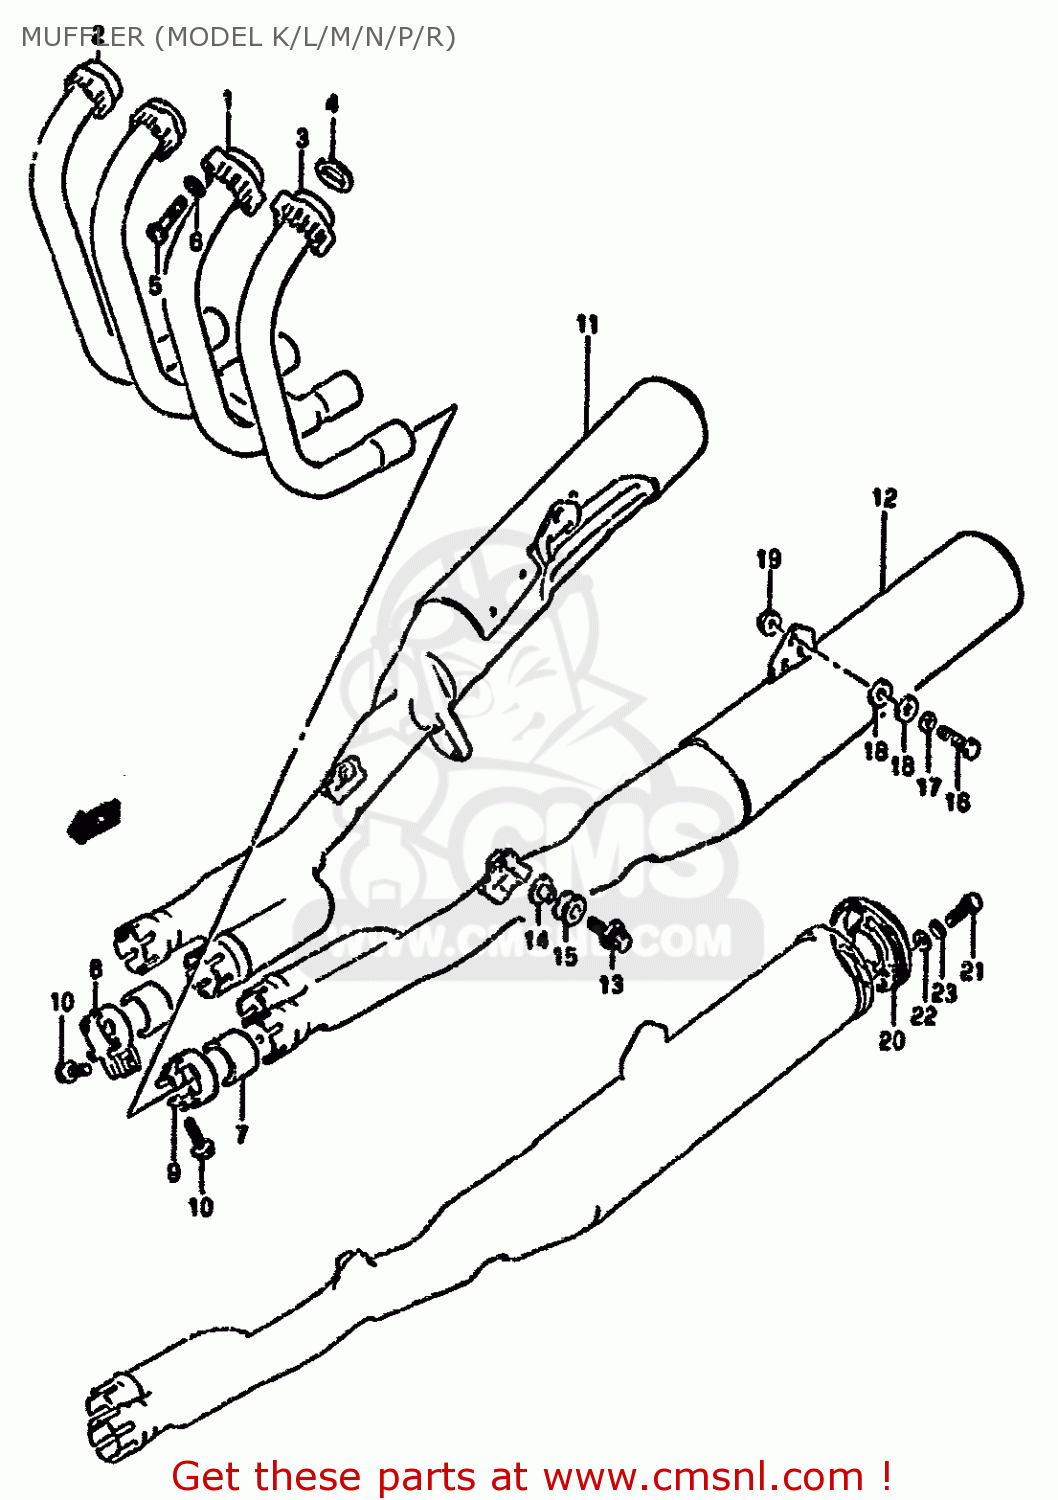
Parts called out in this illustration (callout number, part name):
1	EXHAUST ASSY,CTR
2	PIPE,EXHAUST RH
3	PIPE,EXHAUST LH
4	GASKET (NAS)
5	BOLT
6	WASHER
7	CONNECTOR,MUFFLER
8	CLAMP,MUFFLER CONNECTOR
9	CLAMP,MUFFLER CONNECTOR
10	BOLT
11	MUFFLER,RH
12	MUFFLER,LH
13	BOLT
14	SPACER(8.6X12X17.5)
15	CUSHION
16	BOLT
17	WASHER,LOCK,10
18	WASHER
19	NUT
20	COVER,MUFFLER TAIL
21	BOLT(6X15)
22	WASHER(7X12X1)
23	WASHER
